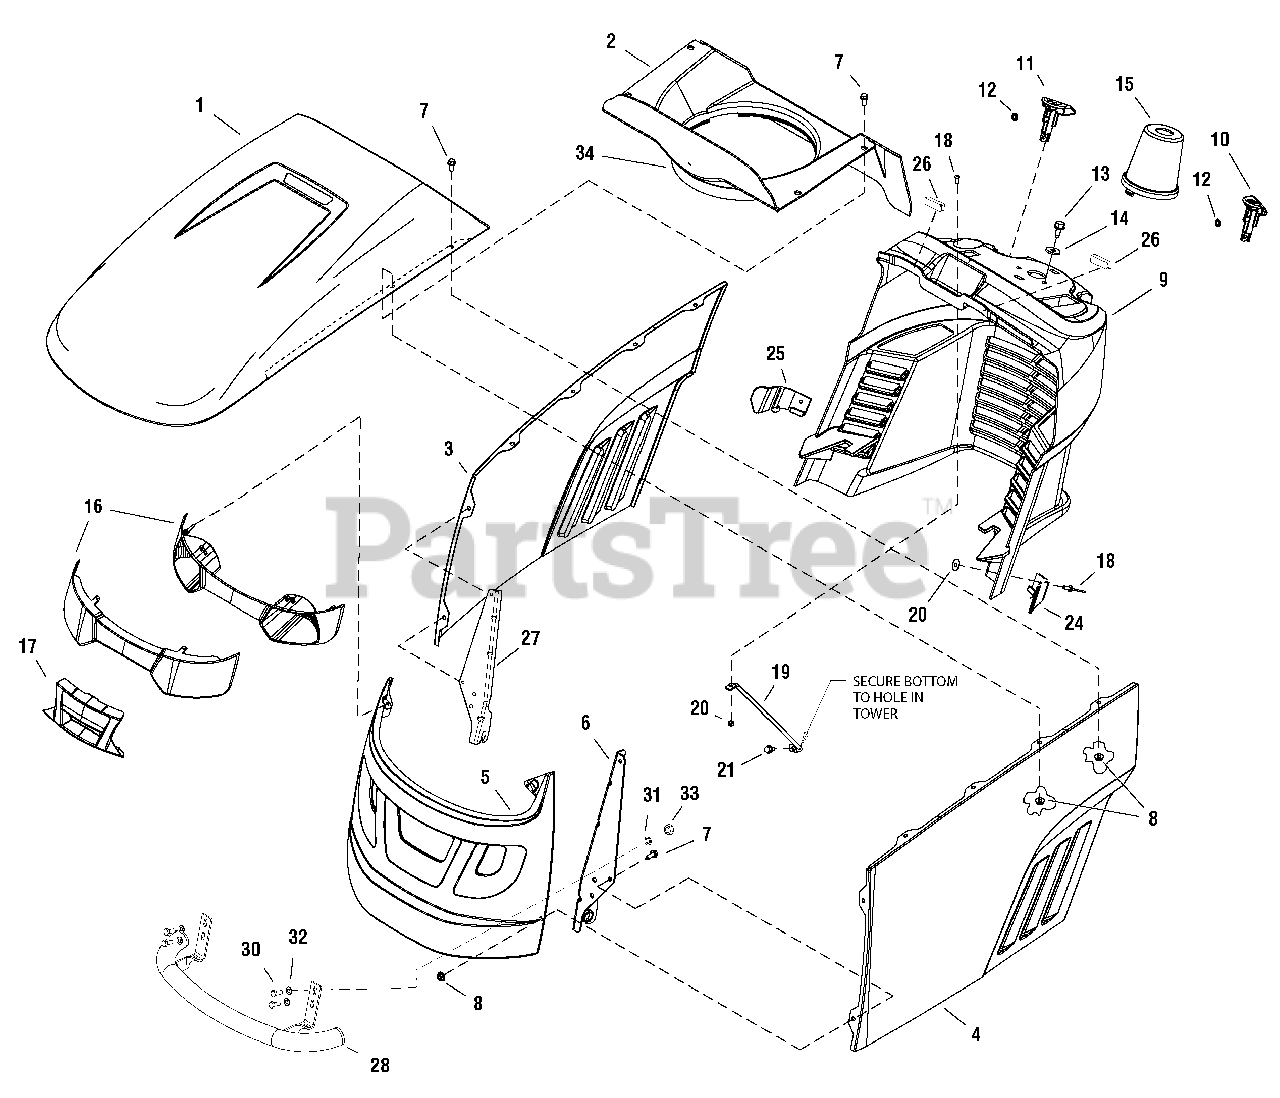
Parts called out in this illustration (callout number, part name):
1	HOOD, With Scoop
2	DUCT, Air Inlet
3	PANEL, Hood, Right
4	PANEL, Hood, Left
5	GRILLE
6	HINGE, Hood Left
7	CAPSCREW, Hex Lock, 1/4-20 X 5/8
8	NUT, Hex Flange Lock, 1/4-20
9	DASHBOARD
10	KNOB, Brake Lock
11	KNOB, Cruise Lock
12	NUT, Push Pal, 1/4
13	CAPSCREW, Hex Tapite, 5/16-18 x 3/4
14	WASHER, 5/16
15	COVER, Steering Shaft
16	HEADLIGHT ASSEMBLY
17	INSERT, Light Bar
18	SCREW, Phillips Head
19	ROD, Dash Support
20	NUT, Flange
21	SCREW, Self Tap
24	GUIDE, Hood Left
25	GUIDE, Hood Right
26	BRAID, Steel-Insert 0-9634-219
27	HINGE, Hood Right
28	BUMPER, Front
30	BOLT, M8 x 20
31	WASHER, 8.4
32	WASHER, 8
33	NUT, M8
34	Ending Rubber
